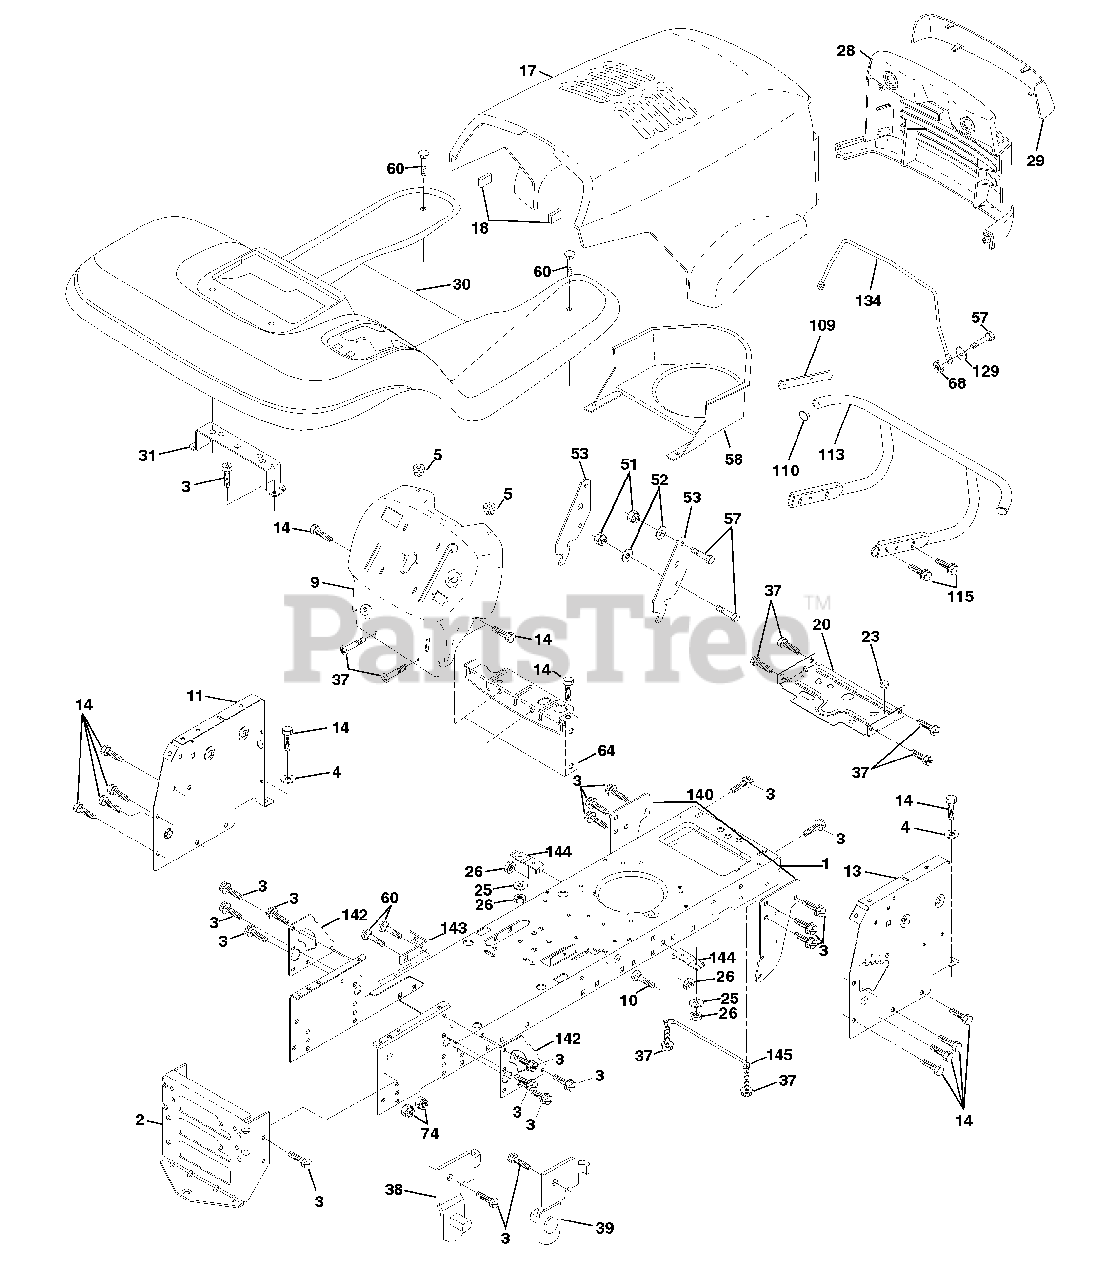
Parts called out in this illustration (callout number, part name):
1	Chassis Weldment
2	Drawbar, Stretch
3	Screw Thdrol 3/8-16x3/4 Ty-tt
4	Washer 13/32 x 3/4 x 16 Ga.
5	Bumper Hood/Dash
9	Dash P/L M, Slkscr Elec N/A N/Hm
10	Bolt Carriage 3/8-16 x 1
11	Panel Dash Lh
13	Panel Dash Rh
14	Screw Thdrol 3/8-16 x 1/2 Ty-tt
17	Hood LT/PL Husqvarna
18	Bumper Hood
20	Plate Mtg Battery Fuel Tank Fr
25	Washer 13/32 X 13/16 X 12 Ga
26	Nut Lock Hex W/Ins 3/8-16 Unc
28	Grille LT/PL Husqvarna
29	Lens LT/PL Husqvarna
30	Fender Footrest STLT Pnt
31	Bracket Support Fender
37	Screw Thdrol 6/16-18 x 1/2 TYT
38	Bracket, Asm. Pivot, L.H., Mower Rear
39	Bracket, Asm. Pivot, R.H., Mower Rear
51	Nut Lock Hex W/Ins 1/4-20
52	Washer 9/32 x 7/8 x 16 Ga.
53	Bracket Pnt. Pick off LT/PL Husqvarna
57	Bolt Hex 1/4-20 x 3/4
58	Air Duct Engine P/L
60	Bolt Rdhd Sqnk 3/8-16unc x 3/4
64	Dash Lower STLT
68	Nut Keps Hex 1/4-20 UNC
74	Nut Crownlock 3/8-16 UNC
109	Bracket Extension, Bumper
110	Plug, Plastic
113	Bumper Asm
115	Screw Thdrol 3/8-16 x 1-1/4
129	Washer 9/32 x 5/8 x 16 Ga.
134	Rod Support Hood Husq.
140	Bracket Front Suspension
142	Plate Reinforcement STLT
143	Bracket Swaybar Chassis
144	Bracket Pnt Footrest STLT
145	Rod Pivot Chassis/Hood
